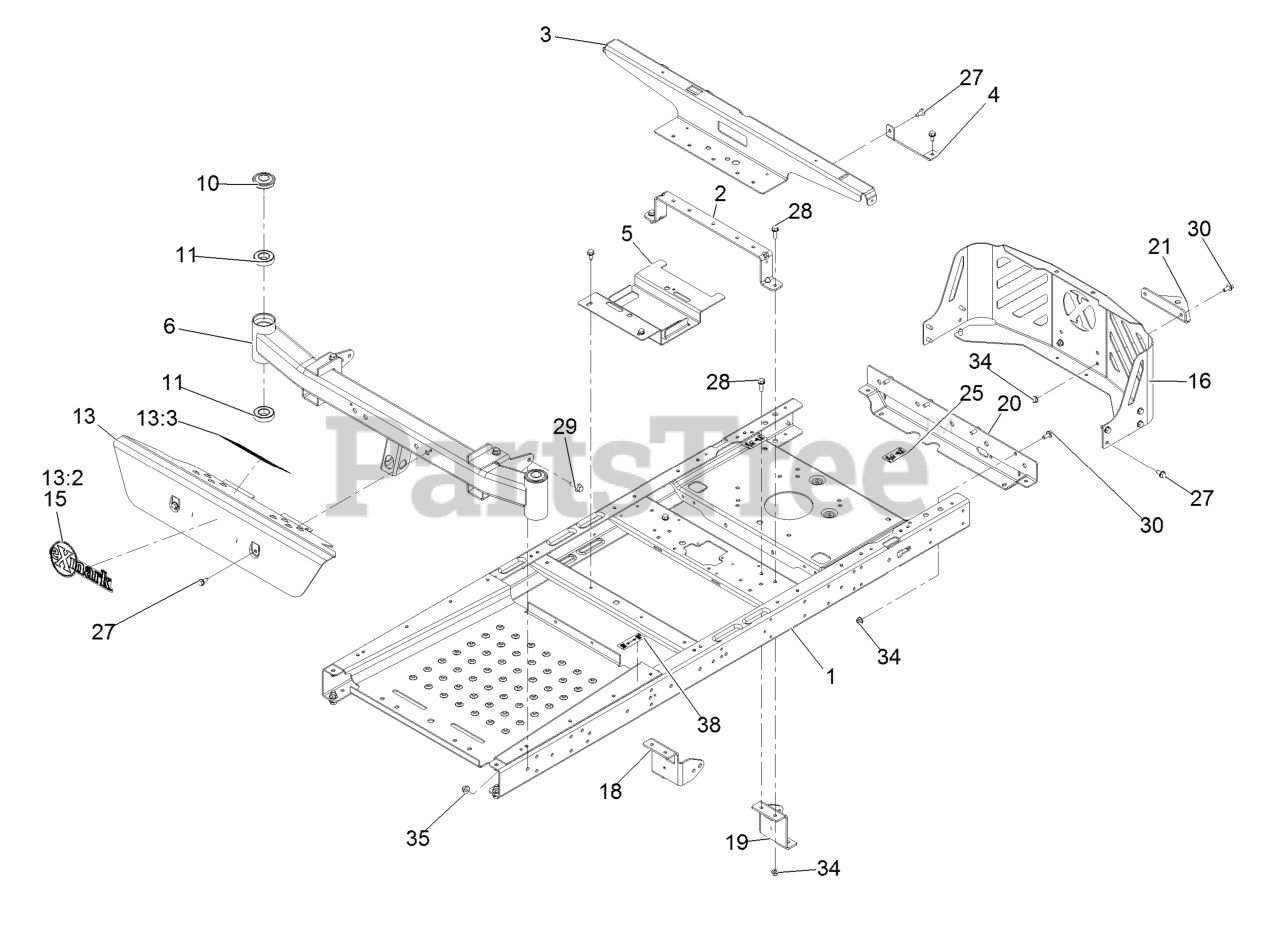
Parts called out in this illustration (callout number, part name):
1	RIVETED FRAME ASM (WIDE LEVER)
2	BRACE-SEAT, REAR (WIDE)
3	SUPPORT-POD
4	SUPPORT-TANK, REAR
5	BRACKET-BATTERY
10	CAP-GREASE
11	BEARING-BALL
13	FOOTREST ASM
13:2	DECAL-EXMARK LOGO
13:3	DECAL-DANGER
15	DECAL-EXMARK LOGO
16	GUARD-ENGINE, WIDE
18	MOUNT-HYDRO, FRONT (RH)
19	MOUNT-HYDRO, FRONT (LH)
20	CROSSMEMBER-REAR, WIDE
21	BRACKET-HITCH
25	DECAL-BYPASS
27	Screw-HWH 5/16-18 X 3/4 Tf
28	SCREW-HHF
29	SCREW-HHF 3/8-16 X 1
30	SCREW-HHF
34	NUT-HF, NI
35	NUT-HF, NI
38	DECAL-BRAKE, PARKING
